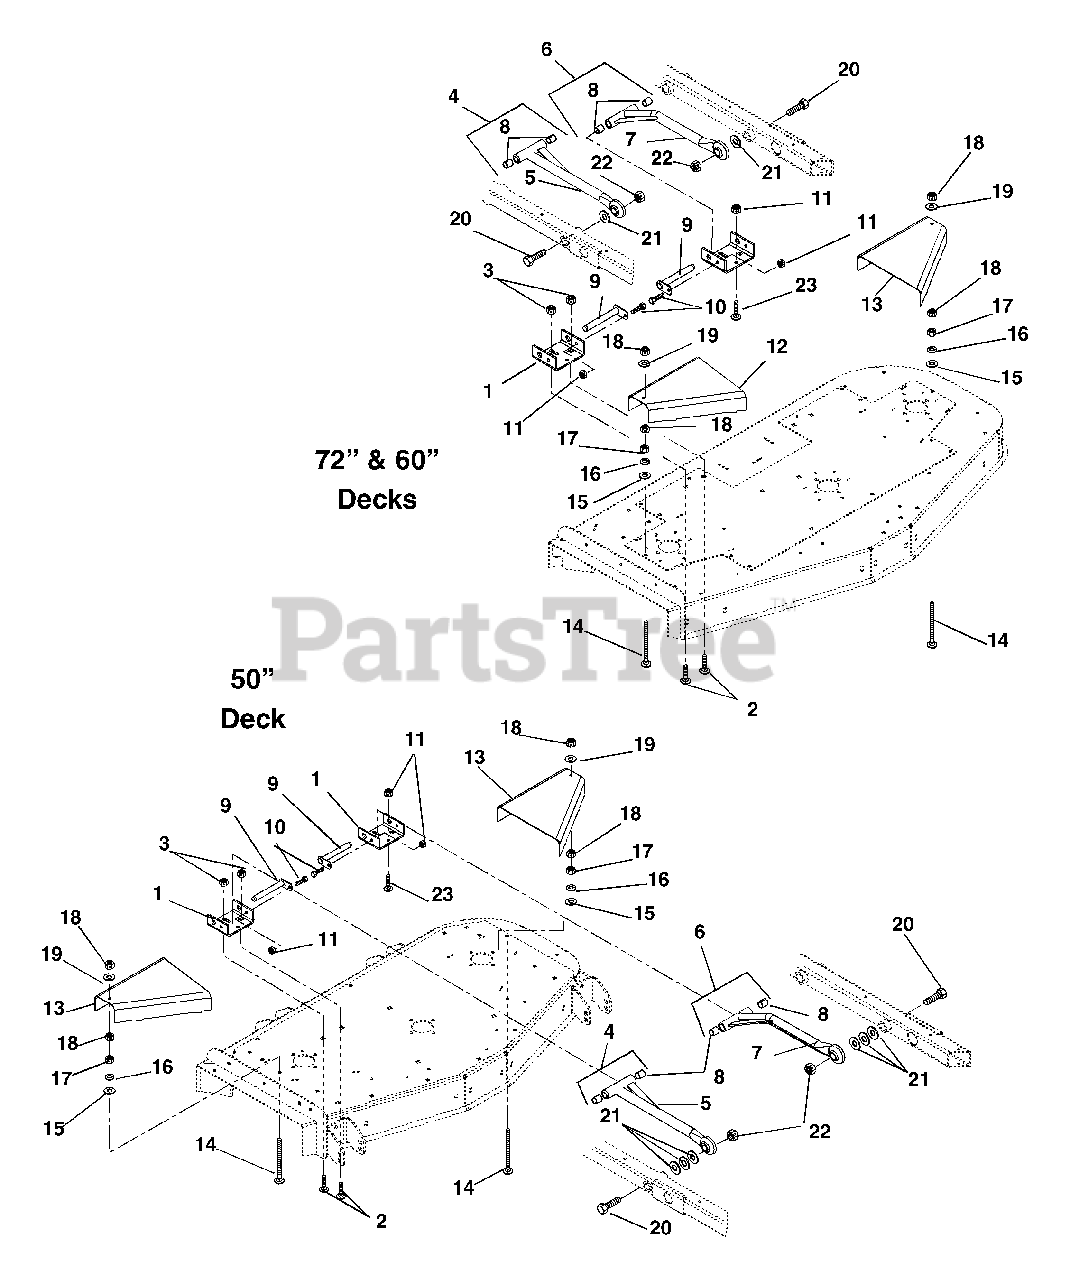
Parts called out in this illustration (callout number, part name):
1	Bracket, Mower Mounting (Rear)
2	Bolt-Round Head Square Neck .50-13 x 1.00 Grade 2
3	Nut-Locking-Center .50-13
4	Assembly, Mower Mounting Arm
5	Weldment-Mower Mounting Arm
6	Assembly, Mower Mounting Arm Left Hand
7	Weldment, Mower Mount Arm
8	Bearing .75 x .875 x 1.00
9	Weldment, Mower Mounting Pin
10	Bolt-Hex .38-16 x .75 Grade 5
11	Nut-Locking-Center .38-16
12	Guard, Pulley Right Hand (60" Deck)
12	Guard, Pulley Right Hand (50" Deck)
12	Guard, Pulley Right Hand (72" Deck)
13	Guard, Pulley Left Hand (60" Deck)
13	Guard, Pulley Left Hand (50" Deck)
13	Guard, Pulley Left Hand (72" Deck)
14	Bolt-Round Head Square Neck .31-18 x 3.50
15	Washer-Flat-Steel .344 x .688 x .065
16	Washer-Locking .31 x .078
17	Nut-Hex .31-18
18	Nut-Locking-Center .31-18
19	Washer-Flat-Steel .438 x 1.00 x.083
20	Bolt-Hex .875-9 x 2.75 Grade 5
21	Washer-Flat-Steel .875 x 1.500 x .1196 (60" & 72" Deck)
21	Washer-Flat-Steel .875 x 1.500 x .1196 (50" Deck)
22	Nut-Locking-Center .875-9
23	Bolt-Round Head Square Neck .38-16 x 1.00 Grade 5
